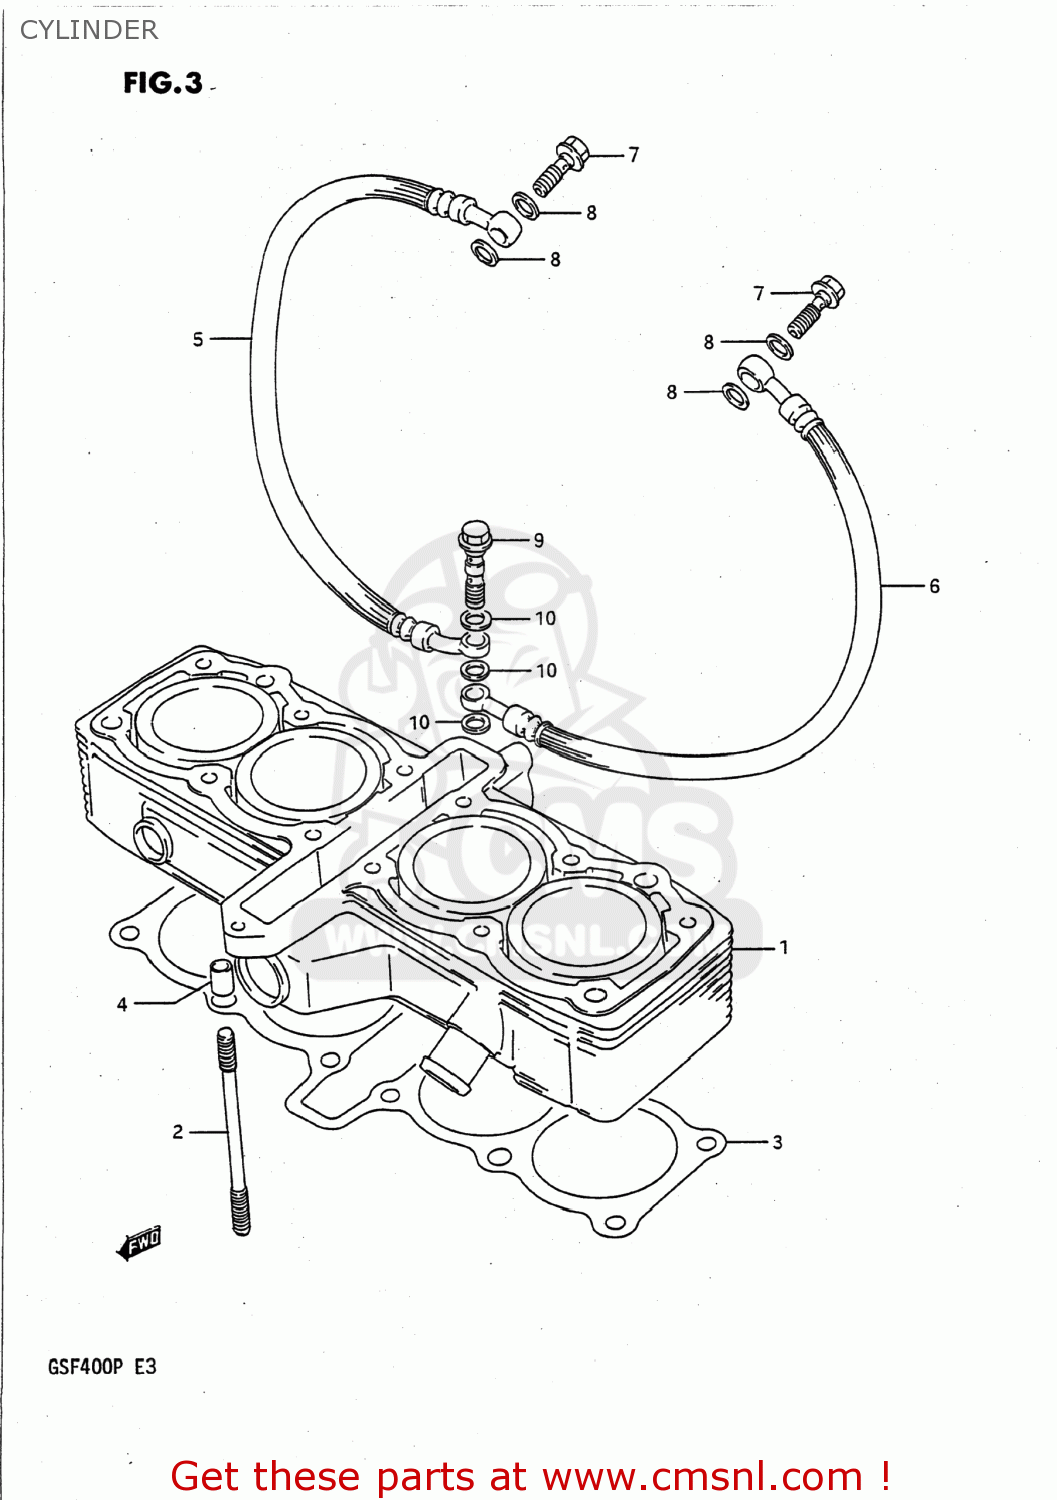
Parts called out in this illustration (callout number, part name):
1	CYLINDER
2	BOLT,STUD(8X120)
3	GASKET,CYLINDER (NAS)
4	PIN
5	HOSE,CRANKCASE OIL,RIGHT
6	HOSE,CRANKCASE OIL,LEFT
7	CLAMP,OIL HOSE CRANKCASE
8	GASKET (NAS)
9	BOLT,OIL PIPE UNION,NO
10	WASHER(10X15X1.5)
